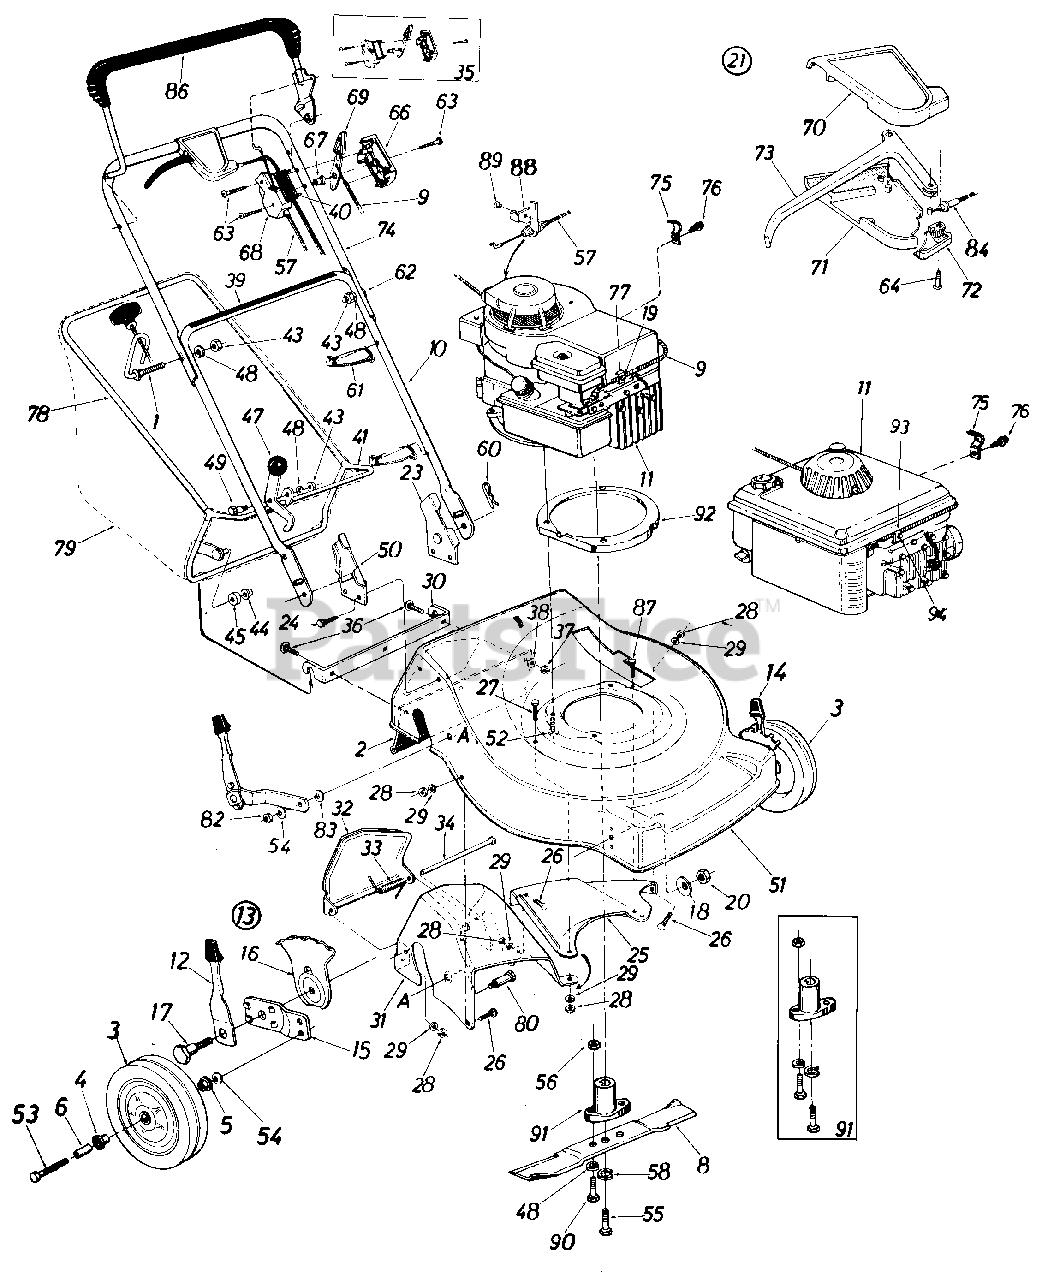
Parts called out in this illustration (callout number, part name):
1	Rope Guide Bolt
2	Rear Flap Ass'y.
3	Front Wheel Ass'y. Comp.
4	Flanged Ball Brg. 1/2" I.D.
5	Flanged Ball Brg. 3/8" I.D.
6	Spacer 3/8" I.D.
8	20" Blade
9	Throttle Control Wire-58"
10	Lower Handle
11	Engine
12	Spring Lever Ass'y. w/Knob
13	Height Adjust. Ass'y.-R.H.
14	Height Adjust. Ass'y.-L.H.
16	Index Plate
17	Shld. Bolt .50" Dia. x .357"
18	Bell-Wash. .39" I.D. x 1.38"
19	Hex Self-Tap Scr. #8 x .38" Lg.
20	Hex Nut 3/8-16 Thd.
21	Clutch Control Housing Comp.
23	Handle Brkt. Ass'y.-L.H.
24	Hex Wash. Hd. AB-Tap Scr. 1/4n x .62" Lg.
25	Rear Baffle-L.H.
26	Carriage Bolt 1/4-20 x .50"*
27	Hex Bolt 1/4-20 x .88" Lg.
28	Hex Nut 1/4-20 Thd.
29	L-Wash. 1/4" I.D.
30	Grass Catcher Hitch Brkt.
31	Rear Chute Baffle Ass'y.
32	Chute Door
33	Torsion Spring
34	Hinge Pin
35	Kit-Control Housing Comp.
36	Carriage Bolt 1/4-20 x .75"*
37	Sems Nut 1/4-20 Thd.
38	Fl-Wash. .285" I.D. x 1.25" O.D.
39	Instruction Label
40	Control Label
41	Grass Catcher Lower Frame Ass'y.
43	Hex Nut 5/16-18 Thd.
44	Push Nut 3/8" Rod
45	Plastic Roller
47	Cam Lever Ass'y.
48	L-Wash. 5/16" I.D.
49	Shld. Bolt .437" Dia. x .180"
50	Handle Brkt. Ass'y.-R.H.
53	Hex Bolt 3/8-16 x 1.75" Lg.
54	Bell-Wash. .44" I.D. x .88" O.D.
55	Hex Bolt 3/8-24 x 2.25" Lg. (Grade 5)
56	Hex Nut 5/16-24 Thd.
57	Control Cable
58	L-Wash. 3/8" I.D. H.D.
60	Intern. Cot. Pin 5/16" Dia.
61	Cable Tie
62	Curved Hd. Carriage Bolt 5/16-18 x 1.38" Lg.
63	Truss Mach. Scr. #12 x 1.50" Lg.
64	Flat "C"-Sunk Hd. Scr. #10 x 1.0" Lg.
66	Control Panel Half
67	Control Disc Pin
68	Clutch Panel Half
69	Throttle Control Lever
70	Control Cover Half-Upper
71	Control Cover Half-Lower
72	Cable Mtg. Cap
73	Control Lever
74	Upper Handle
75	Casing Clamp
76	Hex B-Tap Scr. #10 x .38"
77	Casing Clamp
78	Grass Catcher Upper Frame
79	Grass Catcher Bag
80	Shld. Bolt .500" Dia. x .685"
82	Hex Jam Nut 3/8-16 Thd.
83	Bell-Wash. .400" I.D.
84	Clutch Cable-50"
86	Control Handle Ass'y.-L.H.
87	Hex Wash. Hd. Self-Tap Scr. 1/4-20 x .75" Lg.
88	Cable Brkt.
89	Pop Rivet
90	Hex Bolt 5/16-24 x 1.0" Lg. Special
91	Blade Adapter Kit
92	Engine Mount Cover
93	Casing Clamp
94	Hex B-Tap Scr. #10 x .62" Lg.
